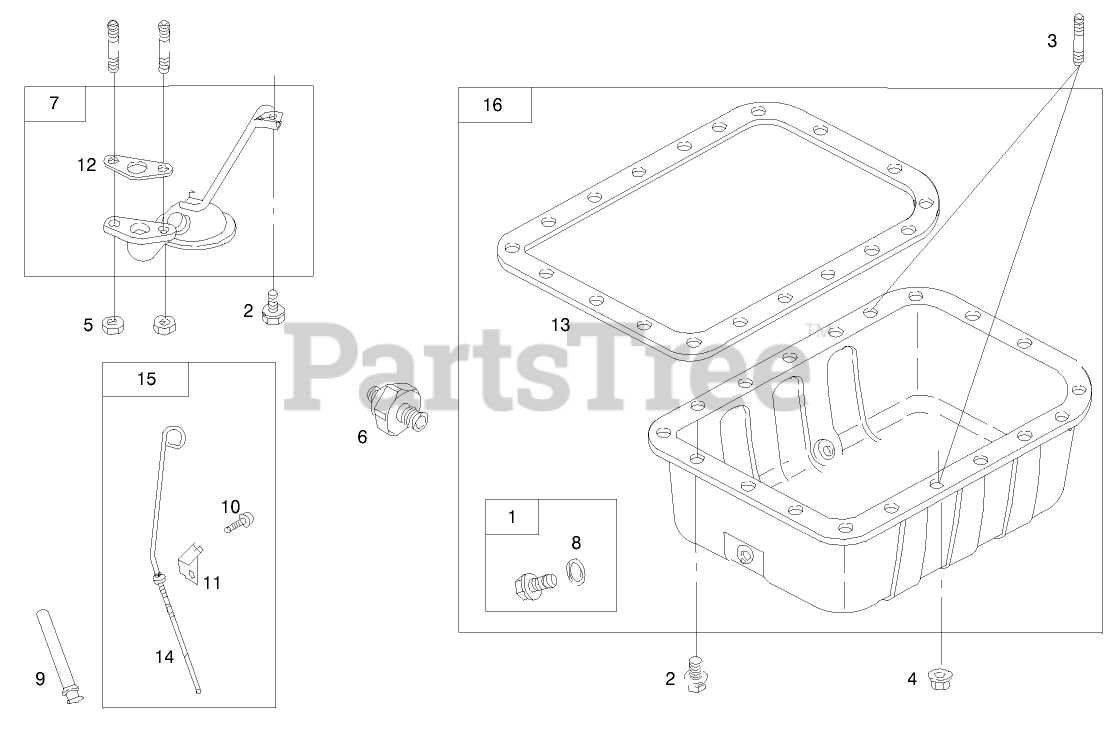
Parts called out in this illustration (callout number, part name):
1	PLUG-DRAIN, OIL
2	SCREW-HEX
3	STUD-METRIC
4	NUT-HEX, METRIC
5	NUT-HEX, METRIC
6	SWITCH-PRESSURE, OIL
7	SCREEN-PUMP, OIL
8	WASHER-SEAL
9	TUBE-DIPSTICK
10	SCREW-HEX
12	GASKET-STRAINER, OIL
13	GASKET-PAN, OIL
14	DIPSTICK
15	DIPSTICK
